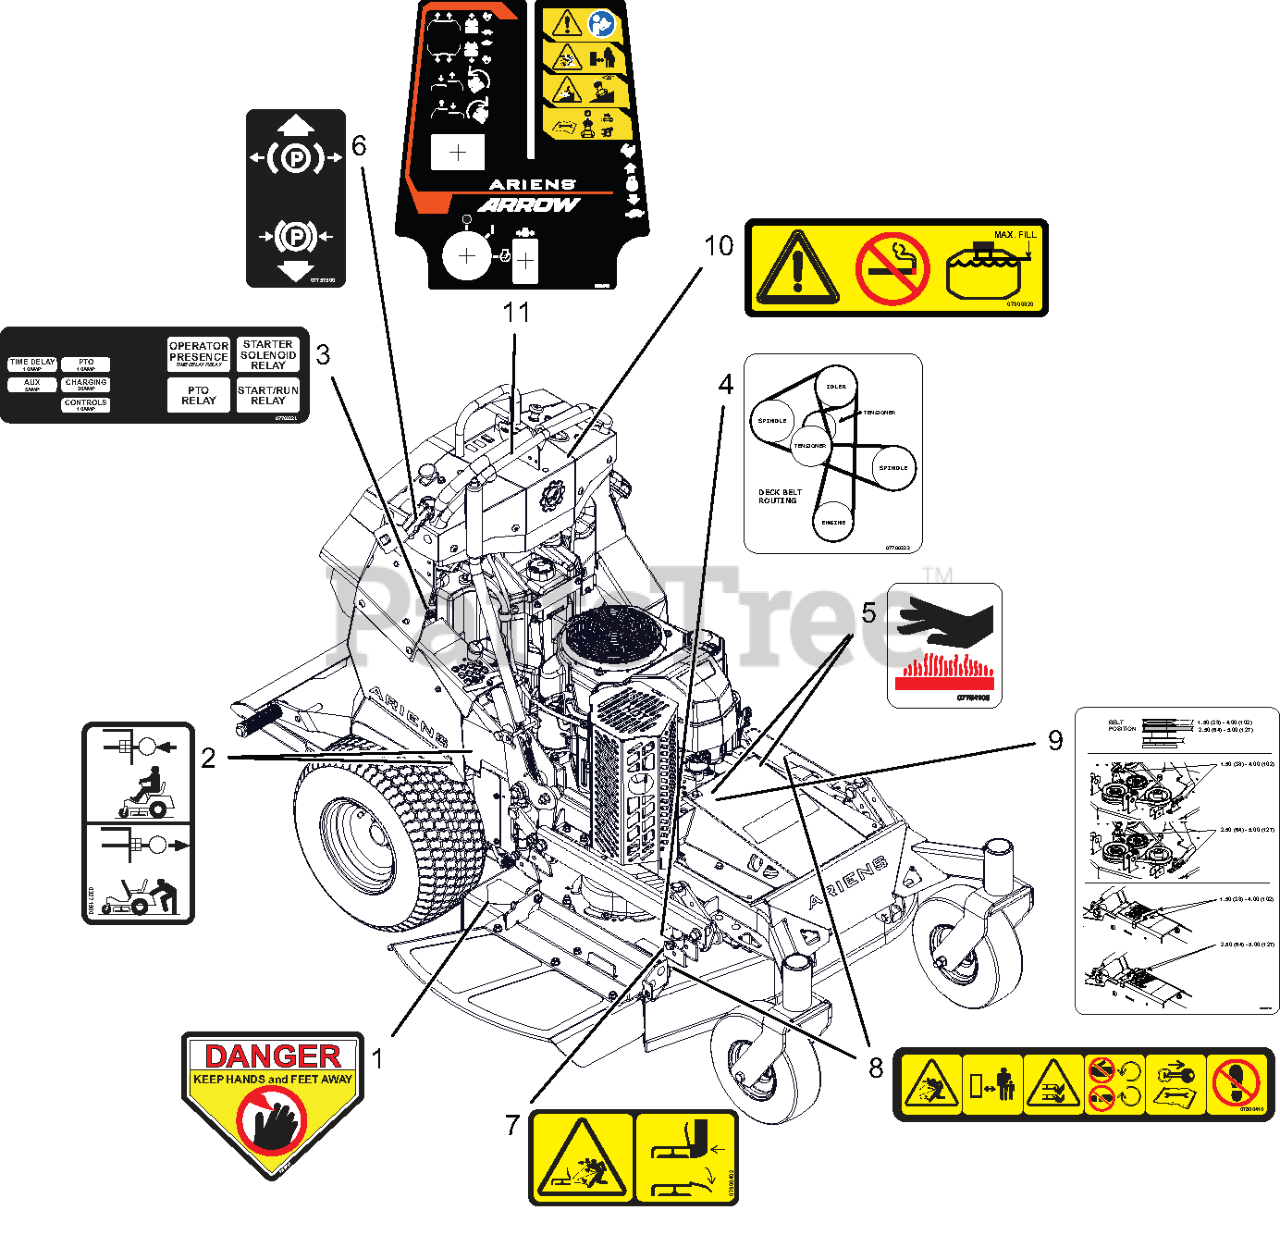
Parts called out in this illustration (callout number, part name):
1	DECAL, DANGER
2	DECAL, TRANSMISSION DISCONNECT
3	DECAL, FUSE BOX
4	DECAL, BELT RTG 32-36" PROSTANCE
5	DECAL, HOT SURFACE
6	DECAL, PARKING BRAKE LEVER
7	DECAL, SAFETY - DECK GUARDING
8	DECAL, DECK SAFETY
9	DECAL, PRO STANCE - HOC ADJUSTMENT
10	DECAL, FUEL WARNING
11	DECAL, DASH - ARROW
